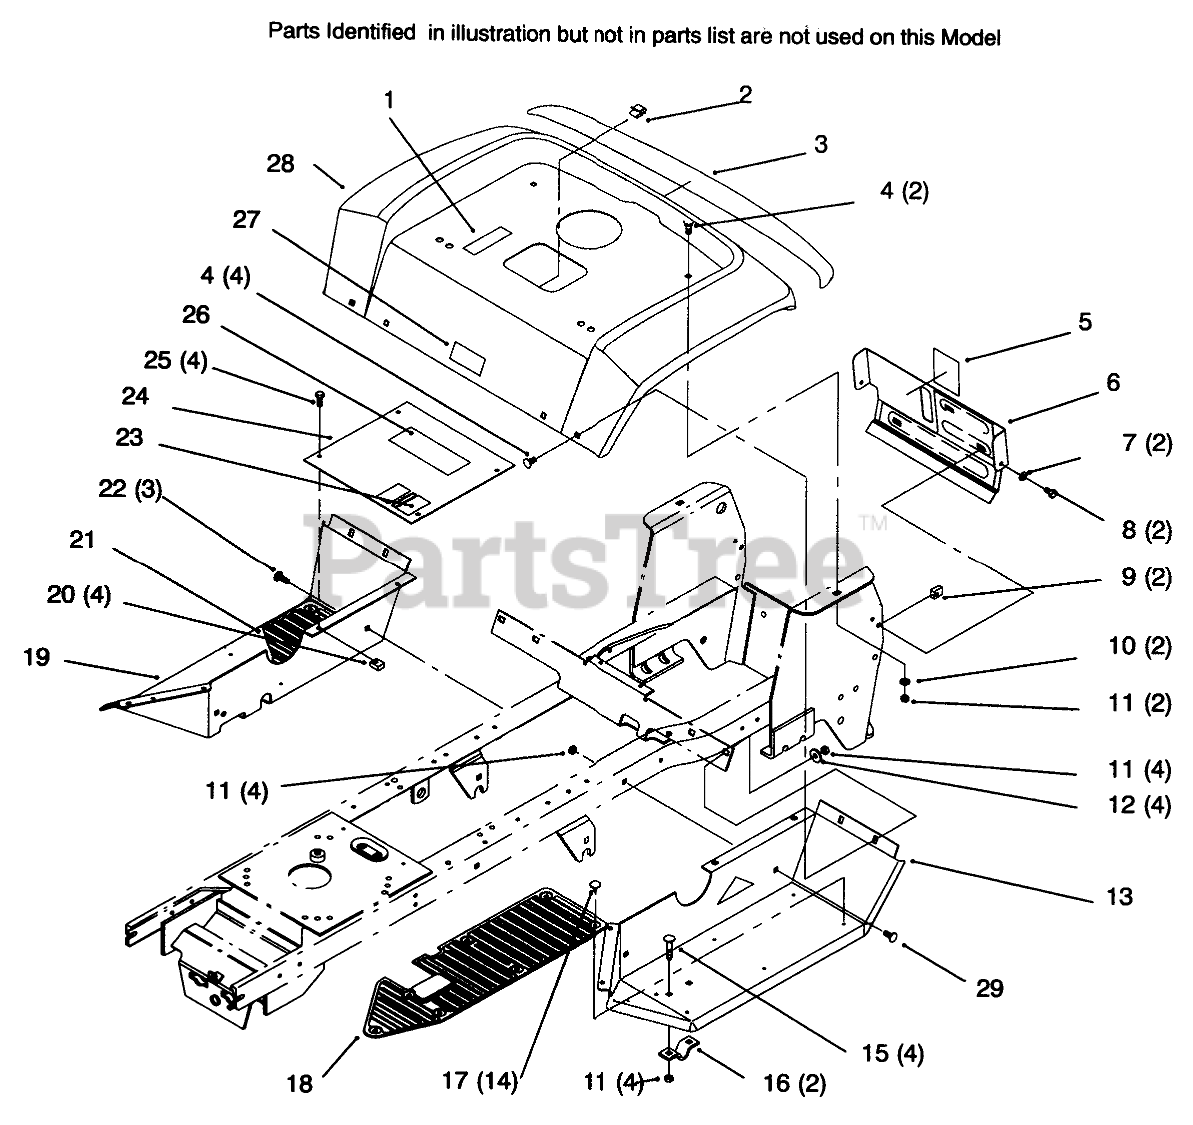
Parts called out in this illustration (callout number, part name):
2	CLIP-RETAINER, WIRE
3	DECAL - REAR FENDER
4	BOLT-CARR
5	DECAL-LEVEL, FUEL
6	WA- REAR COVER (BLACK)
7	WASHER-FLAT
8	SCREW-HH
9	NUT-SPEED
10	WASHER-PLAIN
11	NUT-LOCK, NI
12	WASHER
13	LH FOOTREST
15	SCREW-CARR
16	CLAMP
17	FASTENER-PANEL
18	FOOT MAT-LH
19	FOOTREST-RH
21	FOOT MAT-RH
22	SCREW-CARR
23	DECAL - HOC
24	PLT - FTREST W/DECAL
25	SCREW-HH
26	DECAL-DANGER
27	DECAL - USA
29	BOLT-CARR
